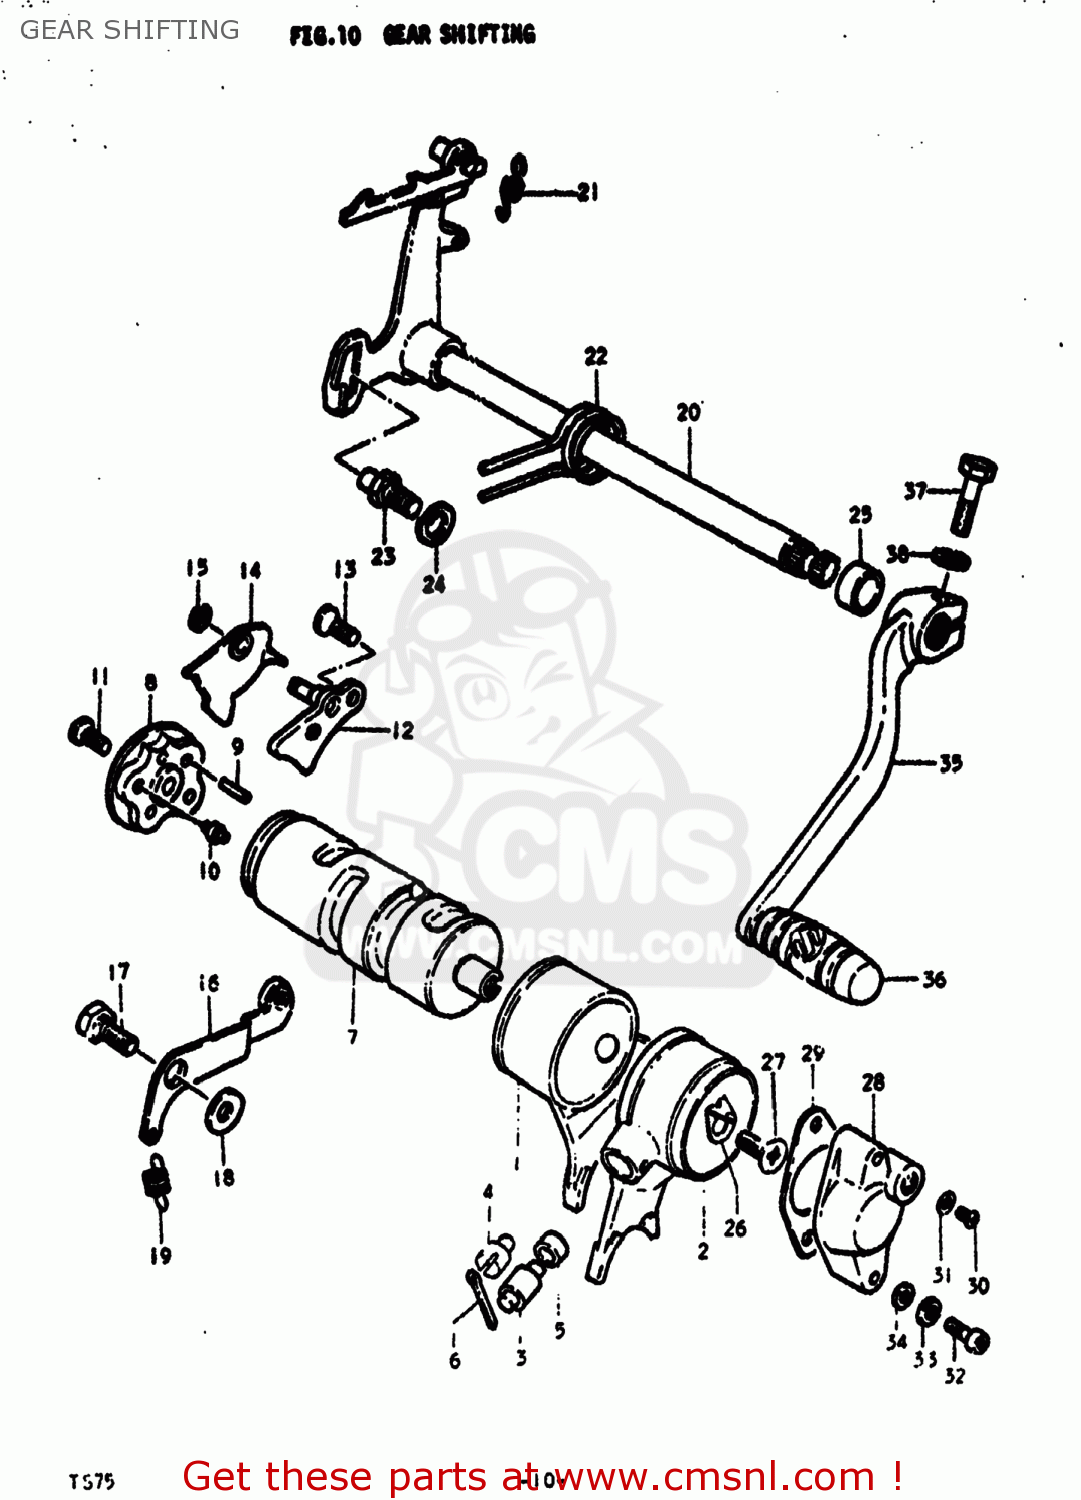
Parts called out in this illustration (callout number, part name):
1	FORK,GEAR SHIFT NO.1
2	FORK,GEAR SHIFT NO.2
3	PIN
4	PIN
5	SPACER
6	PIN 25X20
7	CAM,GEAR SHIFT
8	PLATE,GEAR SHIFT CAM
9	PIN(4X18.5)
10	PIN
11	SCREW
12	GUIDE,GEAR SHIFT CAM
13	SCREW
14	PAWL,GEAR SHIFTING CAM
15	E RING
16	STOPPER,SHIFT CAM
17	BOLT(6X16.1)
18	WASHER(6.5X16X2.3)
19	SPRING
20	SHAFT,GEAR SHIFT
21	SPRING
22	SPRING
23	STOPPER,GEAR SHIFT ARM
24	LOCK WASHER
25	OIL SEAL
26	CONTACT,GEAR SHIFT SWITCH
27	SCREW
28	BODY,GEAR SHIFT SWITCH
29	30
30	SCREW
31	WASHER
32	SCREW
33	LOCK WASHER
34	WASHER
35	LEVER ASSY,GEAR SHIFT
36	RUBBER,GEAR SHIFT PEDAL
37	BOLT
38	LOCK WASHER
